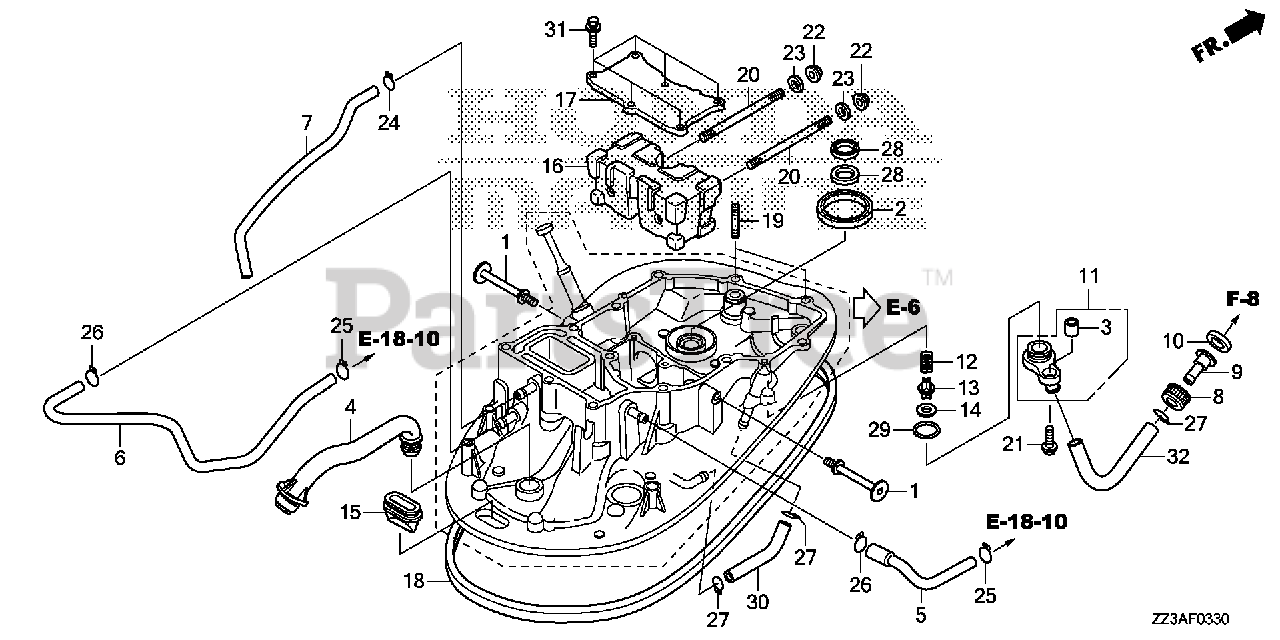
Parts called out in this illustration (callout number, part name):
1	STOPPER, ENGINE SIDE
2	RUBBER, OIL PUMP
3	COLLAR, DISTANCE
4	PORT, IDLE EX.
5	TUBE A, WATER
6	TUBE B, WATER
7	TUBE C, WATER
8	NUT, WATER MOUTH
9	JOINT, WATER HOSE
10	SEAT, WATER MOUTH
11	COVER, FLUSH VALVE
12	SPRING, FLUSH VALVE
13	VALVE, FLASH
14	GASKET, FLASH VALVE
15	RUBBER, MOUNT CASE SEAL
16	MOUNT, RUBBER (UPPER)
17	COVER, MOUNT (UPPER)
18	SEAL A, COVER (LOWER)
19	BOLT 2, STUD (8X25)
20	BOLT, STUD (10X125)
21	BOLT, FLANGE (6X20)
22	NUT, FLANGE (10MM)
23	WASHER, PLAIN (10MM)
24	CLIP, TUBE (B10)
25	CLIP, TUBE (B12)
26	CLIP, TUBE (B12.5)
27	CLIP B1, TUBE
28	SEAL, WATER (17X26X7)
29	O-RING (16MM)
30	TUBE, FLUSH VALVE
31	BOLT-WASHER (6X20)
32	BULK HOSE, FUEL (8X1000) (8X130)
